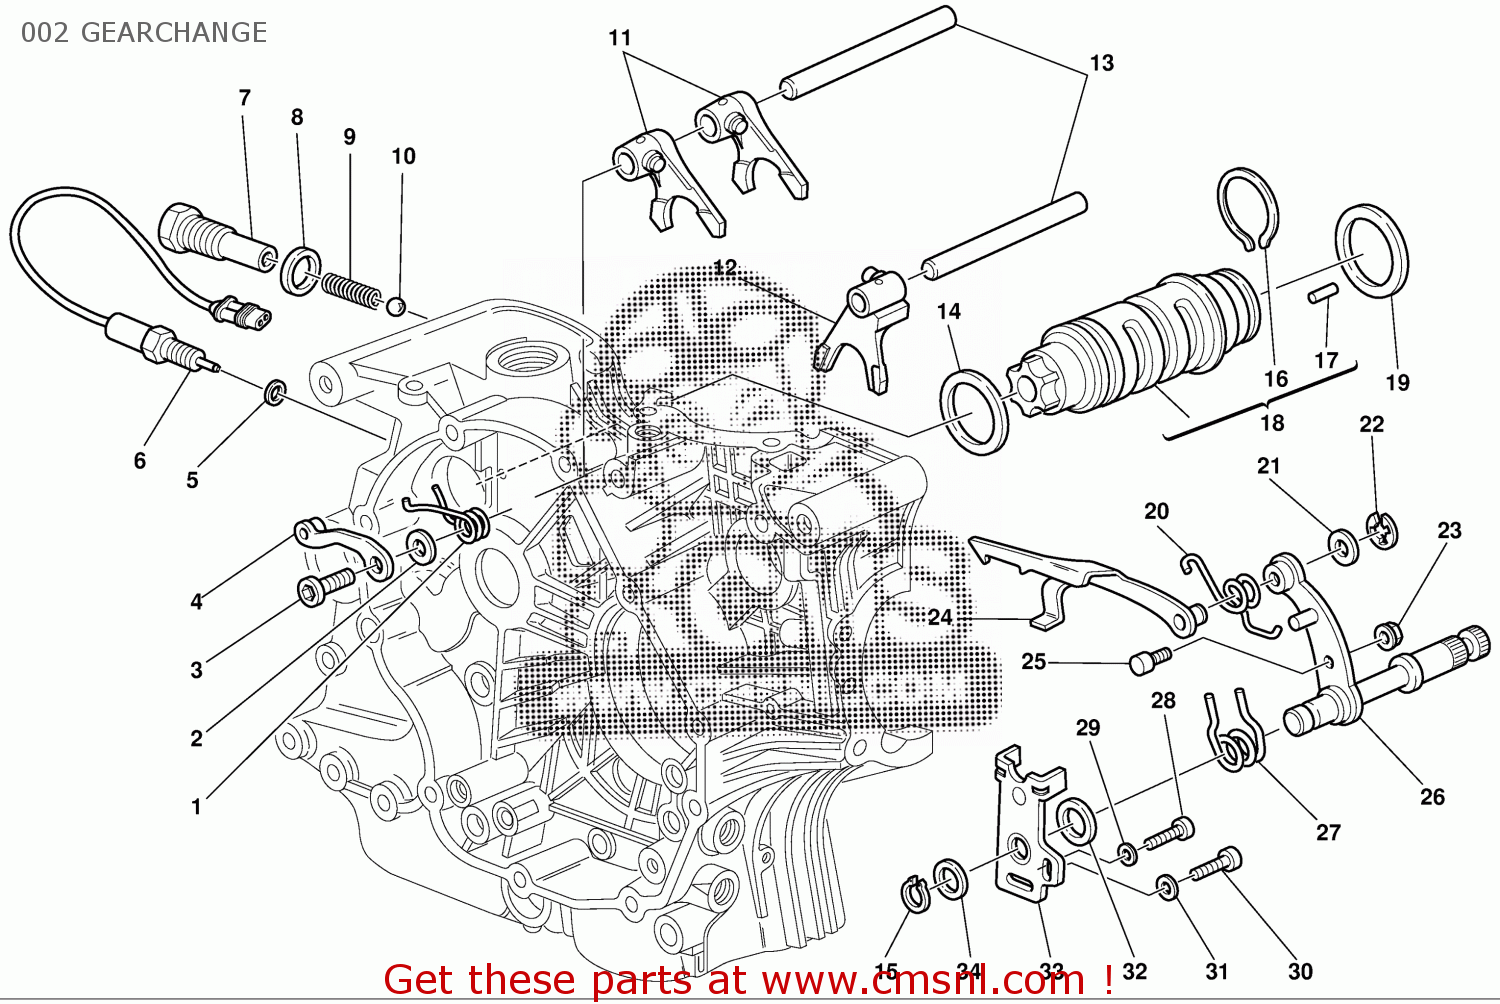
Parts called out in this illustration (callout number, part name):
1	SPRING, RETURN
2	WASHER 8.2X20X1
3	SCREW M8X21.5
4	GEAR FIXING CLICK ASSEMBLY
5	GASKET 2 MM
6	NEUTRAL SWITCH ASSY
7	SCRE M16X1.5, SPRING SEAT
8	GASKET 16.2X24X2
9	GEAR SELECTOR SPRING
10	BALL 11MM
11	SHIFT FORK 1ST-4TH 2ND-3RD
12	SHIFT FORK 5TH-6TH
13	AXLE, GEAR SHIFT FORK 10X116 MM
14	THRUST WASHER 1 MM
15	CIRCLIP 15 DIN 471
16	NEEDLE RETAINING RING
17	SPECIAL ROLLER
18	CAM, GEAR SHIFT
19	THRUST WASHER 45.2X49X1.0
20	RETURN SPRING
21	THRUST WASHER 10.5X16X0.5
22	RING, BENZING 8MM DIN 6799
23	SELF LOCKING NUT M6 H5.5
24	CONTROL FORK
25	GEARCHANGE LEVER PIN
26	GEAR SELECTOR SHAFT
27	SPRING, SHIFT RETURN
28	BOLT, SOCKET HEAD M6X20
29	WASHER
30	SCREW M8X18
31	WASHER
32	CENTERING RING
33	STOPPER PLATE
34	THRUST WASHER 15.5X22X0.2
